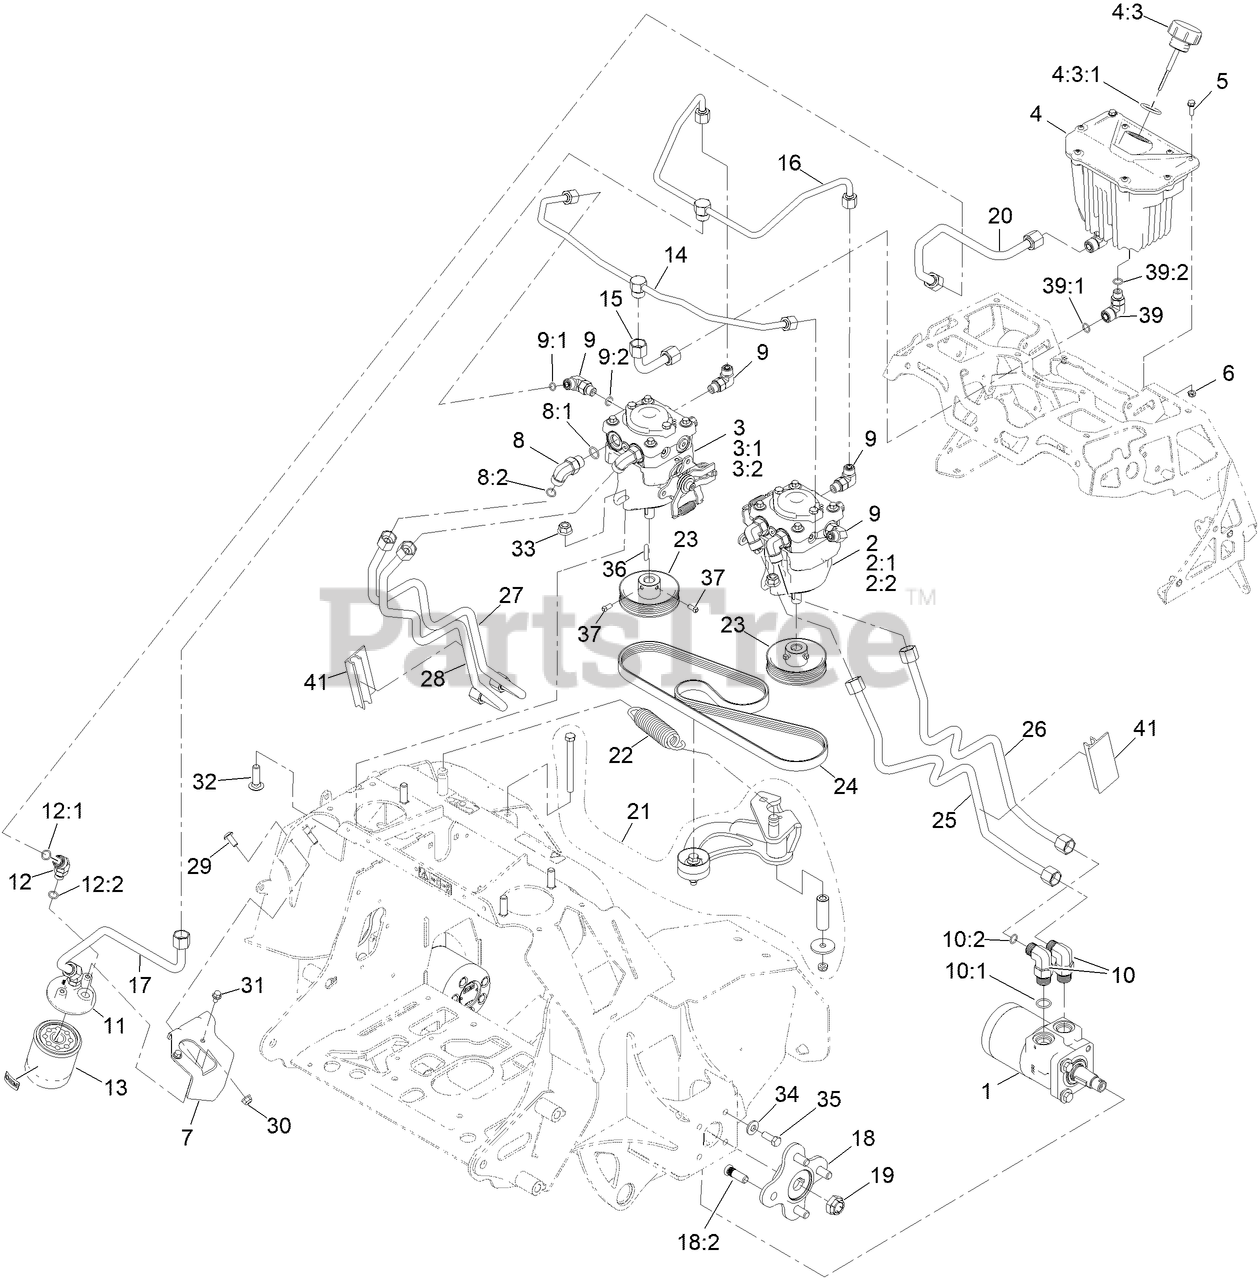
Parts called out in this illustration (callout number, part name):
1	MOTOR-WHEEL
2	PUMP-HYDRAULIC 10CC
2:1	KIT, 10CC/12CC PUMP KIT
2:2	SEAL OVERHAUL KIT
3	PUMP-HYDRAULIC 10CC
3:1	KIT, 10CC/12CC PUMP KIT
3:2	SEAL OVERHAUL KIT
4	HYDRAULIC RESERVOIR ASM
4:3	CAP, HYDRAULIC
4:3:1	O-RING
5	SCREW-HWH
6	NUT-LOCK, NI
7	MOUNT, FILTER
8	FITTING-ELBOW, 90 DEG
8:1	O-RING
8:2	O-RING
9	FITTING-ELBOW, 90 DEG
9:1	O-RING
9:2	O-RING
10	FITTING-ELBOW, 90 DEG
10:1	O-RING
10:2	O-RING
11	HEAD-FILTER
12	ADAPTER
12:1	O-RING
12:2	O-RING
13	ELEMENT-FILTER, 25 MICRON
14	LINE, HYDRAULIC, CASE TEE
15	LINE, HYDRAULIC, CASE
16	LINE, HYDRAULIC, CHARGE TEE
17	LINE, HYD. CHARGE
18	ASM-HUB AND STUDS
18:2	STUD-WHEEL
19	NUT-LOCK
20	LINE, HYD. SUPPLY
21	ASM, IDLER ARM
22	SPRING, EXTENSION
23	PULLEY, PVK5
24	BELT PVK5
25	KIT-STE HYD LINE LT REAR B-A
26	KIT-STE HYD LINE LT FRNT A-B
27	KIT-STE HYD LINE RT REAR B-B
28	KIT-STE HYD LINE RT FRNT A-A
29	SCREW-TORX
30	NUT-HF, NI
31	SCREW-HHF
32	BOLT-CARR
33	NUT-HF, NI
34	WASHER-BELLEVILLE
35	SCREW-HH
37	SCREW-SQH
39	FITTING-HYD, 90 DEG
39:1	O-RING
39:2	O-RING
41	SPACER-HYDRAULIC TUBE
